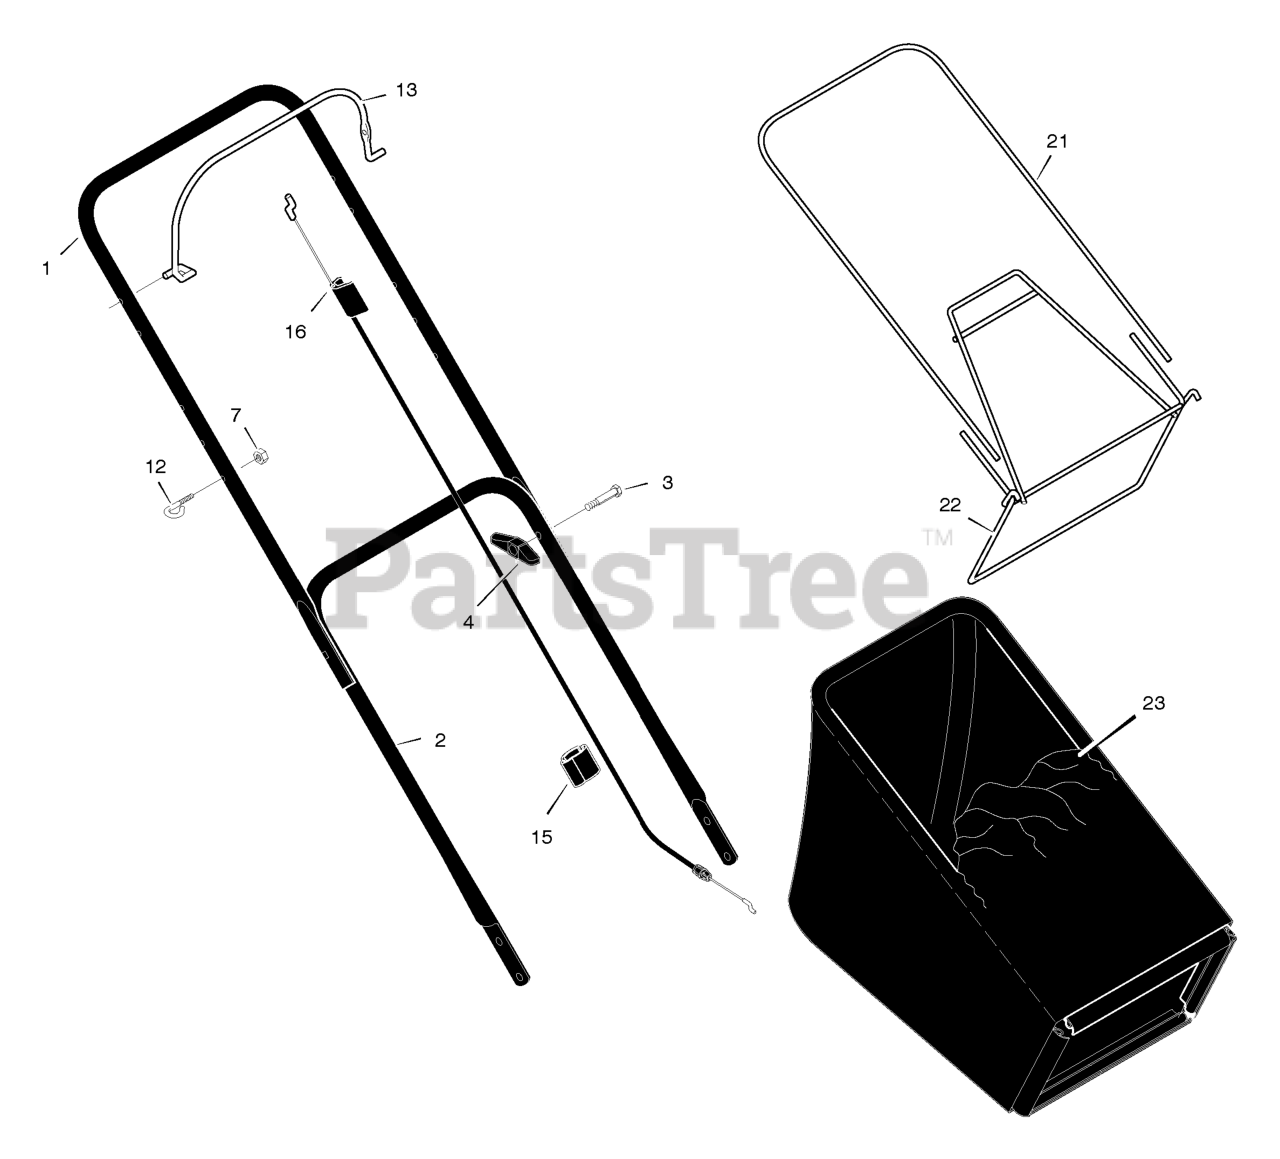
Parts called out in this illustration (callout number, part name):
1	Handle, Upper (Gray)
2	Handle, Lower (Gray)
4	Knob, Plastic
7	Locknut
12	Guide, Rope
13	Engine Stop Lever
15	Fastener, Cable
16	Engine Stop Cable
21	Frame, Top
22	Frame Assembly
23	Bag, Cloth
